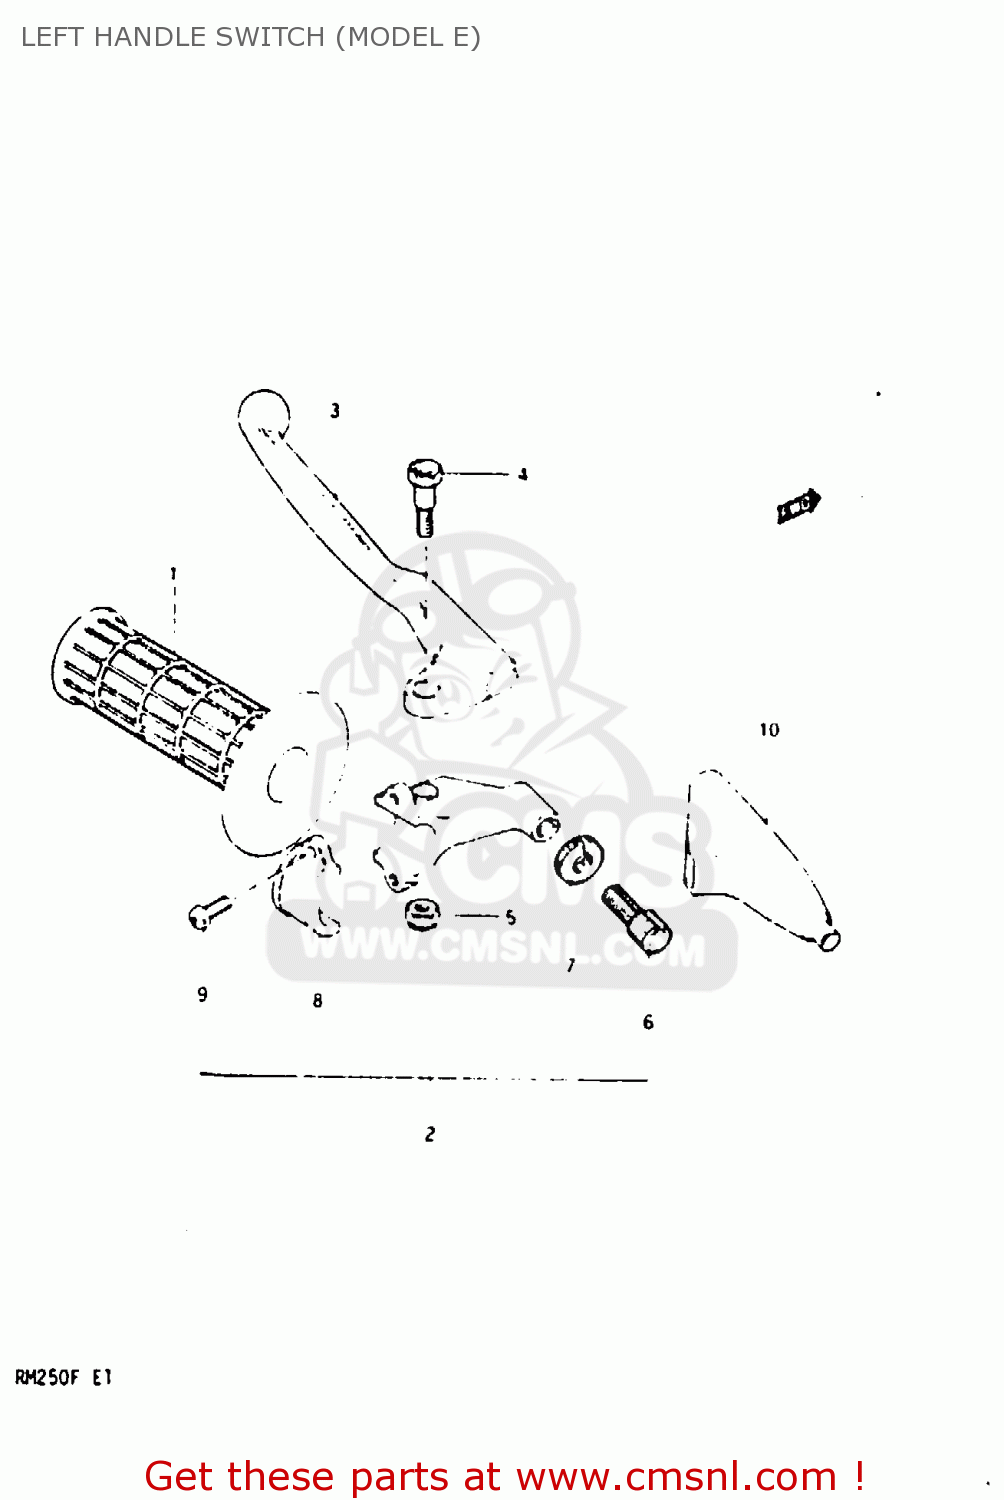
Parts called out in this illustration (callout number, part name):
1	GRIP,LEFT
2	LEVER ASSY,CLUTCH
3	LEVER,CLUTCH
4	BOLT,LEVER
5	NUT 6MM
6	ADJUSTER,CABLE
7	NUT,CABLE ADJUSTER
8	BRACKET,CLUTCH LEVER HOLDER
9	SCREW
10	COVER,CLUTCH LEVER
